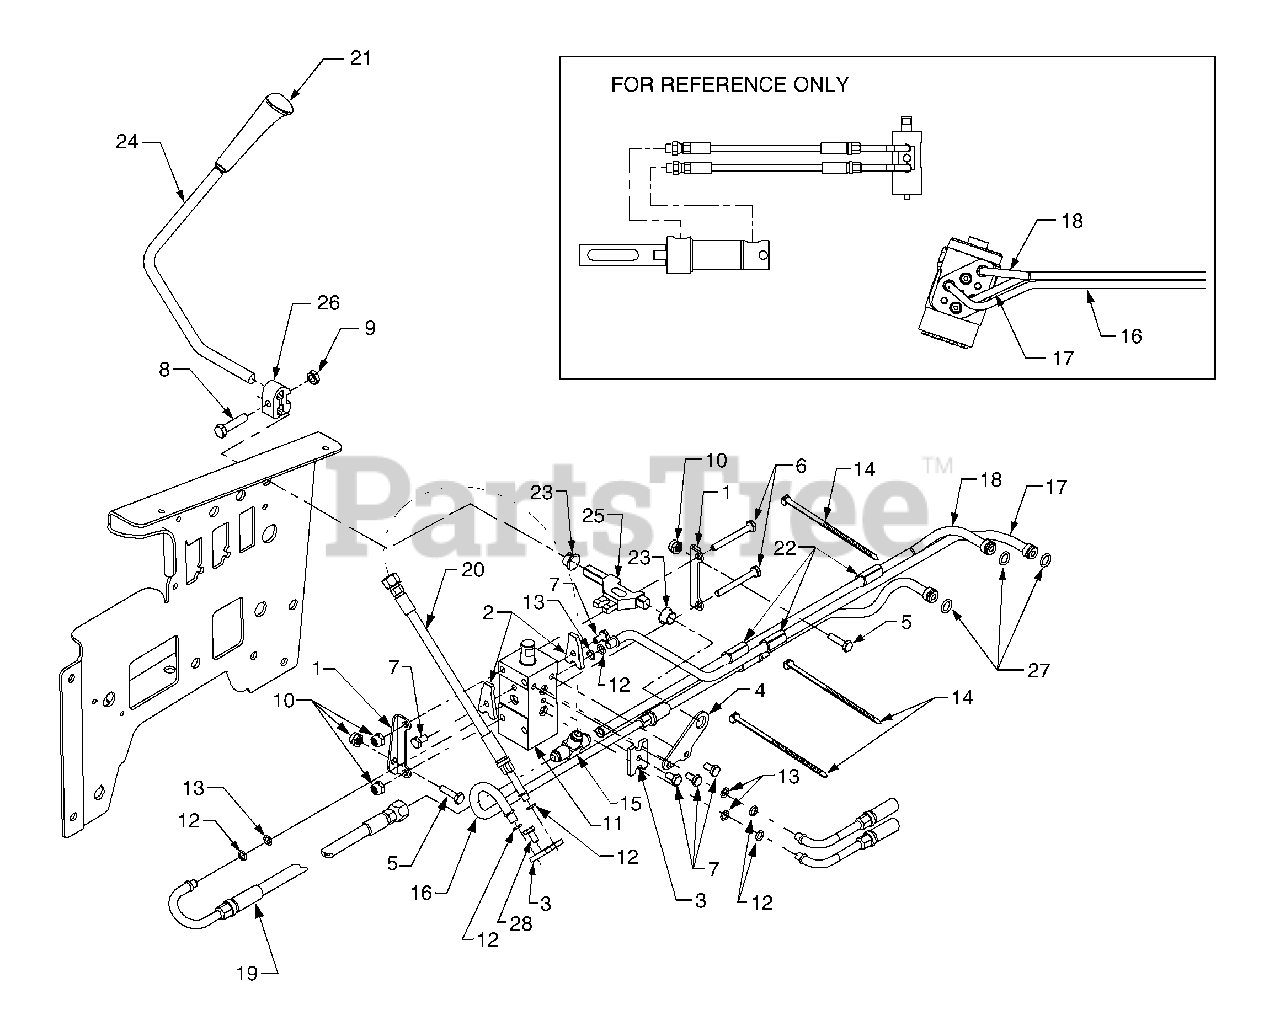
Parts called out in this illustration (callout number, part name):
1	Bracket, Valve Mounting
2	Clamp, Side Valve
3	Clamp, Double Valve
5	Screw, Hex Cap 1/4-20 x 1.0 GR5
6	Screw, Hex Cap 1/4-20 x 2.25 GR5
7	Screw, Hex Cap 1/4-20 x .50 GR5
8	Screw, Hex Cap 5/16-18 x 1.375 GR5
9	Nut, Hex Insert Lock, 5/16-18
10	Nut, Hex Flange Lock, 1/4-20
11	Valve, Hydraulic
12	O-Ring, Backup
13	O-Ring
14	Cable Tie
15	T-Fitting, 9/16-18 Thrd.
16	Tube, Hydraulic
17	Tube, Hydraulic
18	Tube, Hydraulic
19	Tube, Hydraulic
20	Tube, Hydraulic
21	Knob, Lift
22	Rubber Spacer
23	Bearing, Nylon Flange
24	Handle, Center Lift Valve
25	Link, Lift
26	Clamp, Handle
27	O-Ring, .426 x .566 x .070
28	Screw, Hex Cap 1/4-20 x .62 GR5
